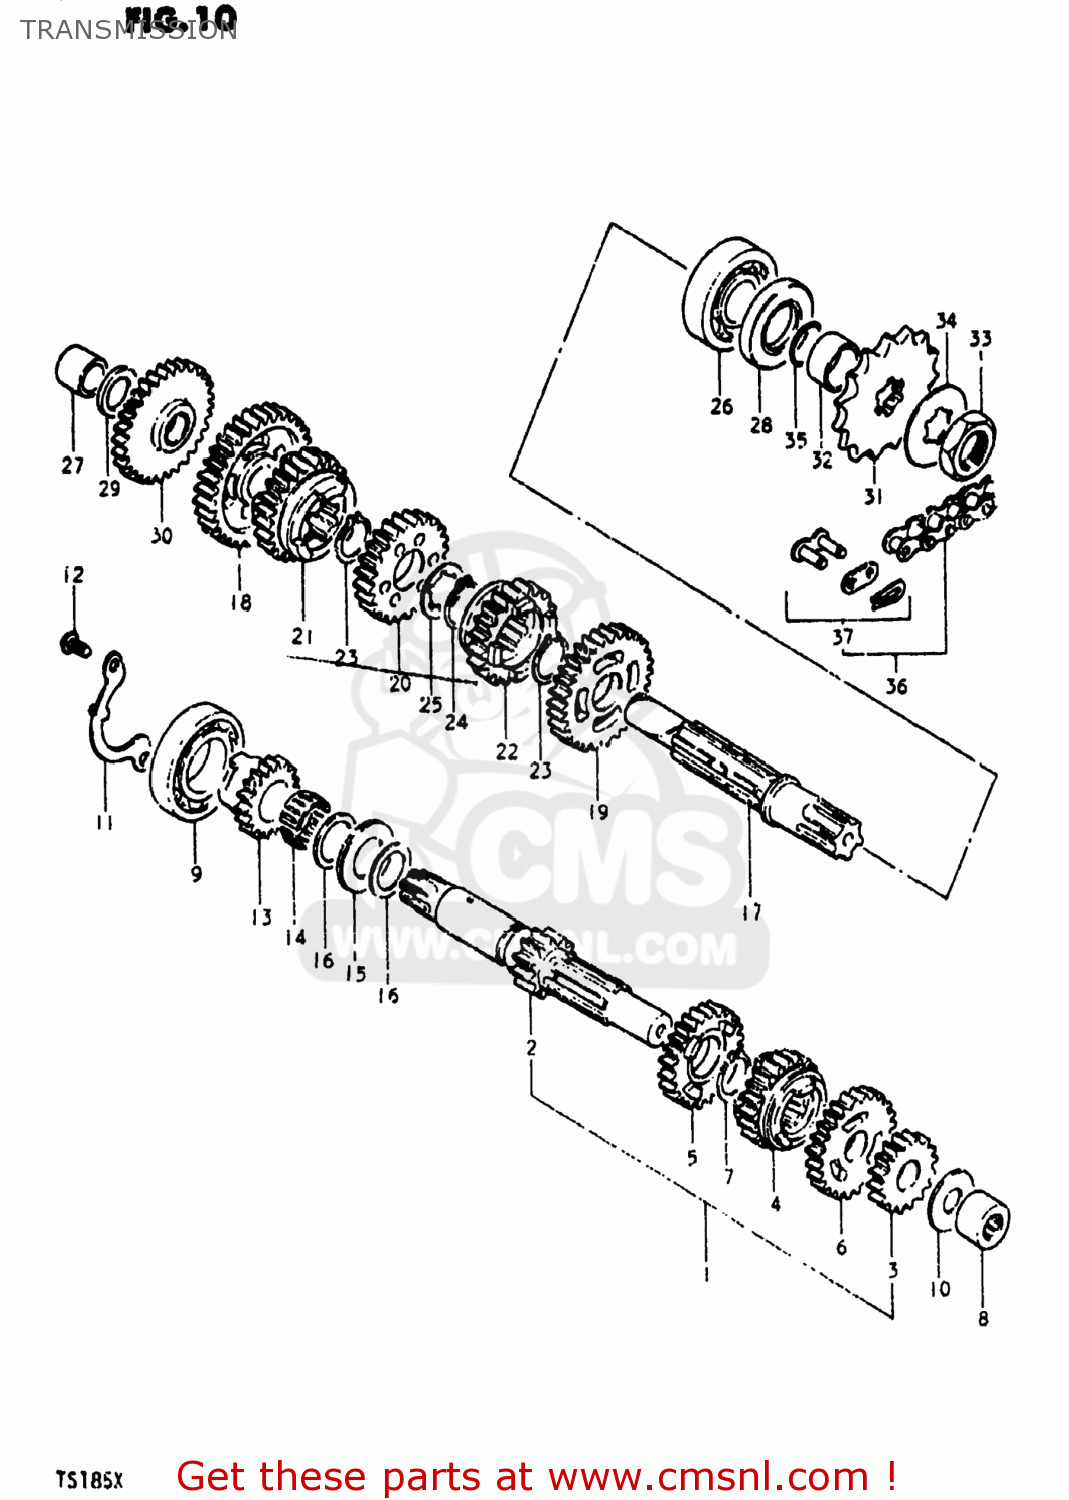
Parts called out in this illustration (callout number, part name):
1	SHAFT,COUNTER
2	SHAFT,COUNTER
3	GEAR,2ND DRIVE
4	GEAR,3RD DRIVE
5	GEAR,FOURTH DRIVE
6	GEAR,5TH DRIVE
7	CIRCLIP
8	BEARING(15X22X15)
9	BEARING, RH
10	WASHER
11	RETAINER,CNTR SHAFT BEARING
12	SCREW 6X12
13	GEAR,KICK STARTER DRIVEN
14	BEARING(19.2X23.2X19)
15	BEARING(21X32X2.85)
16	WASHER(21X30X0.8)
17	SHAFT,DRIVE
18	GEAR,1ST DRIVEN
19	GEAR,2ND DRIVEN
20	GEAR,THIRD DRIVEN
21	GEAR,FOURTH DRIVEN
22	GEAR,FIFTH DRIVEN
23	CIRCLIP
24	CIRCLIP
25	WASHER
26	BEARING
27	BUSH
28	OIL SEAL (25X44X7)
29	WASHER
30	GEAR,KICK STARTER IDLE
31	SPROCKET,ENGINE
32	SPACER(20X25X12.5)
33	NUT
34	WASHER,LOCK
35	O RING(D:1,ID:19.5)
36	CHAIN ASSEMBLY,DRIVE
37	JOINT
